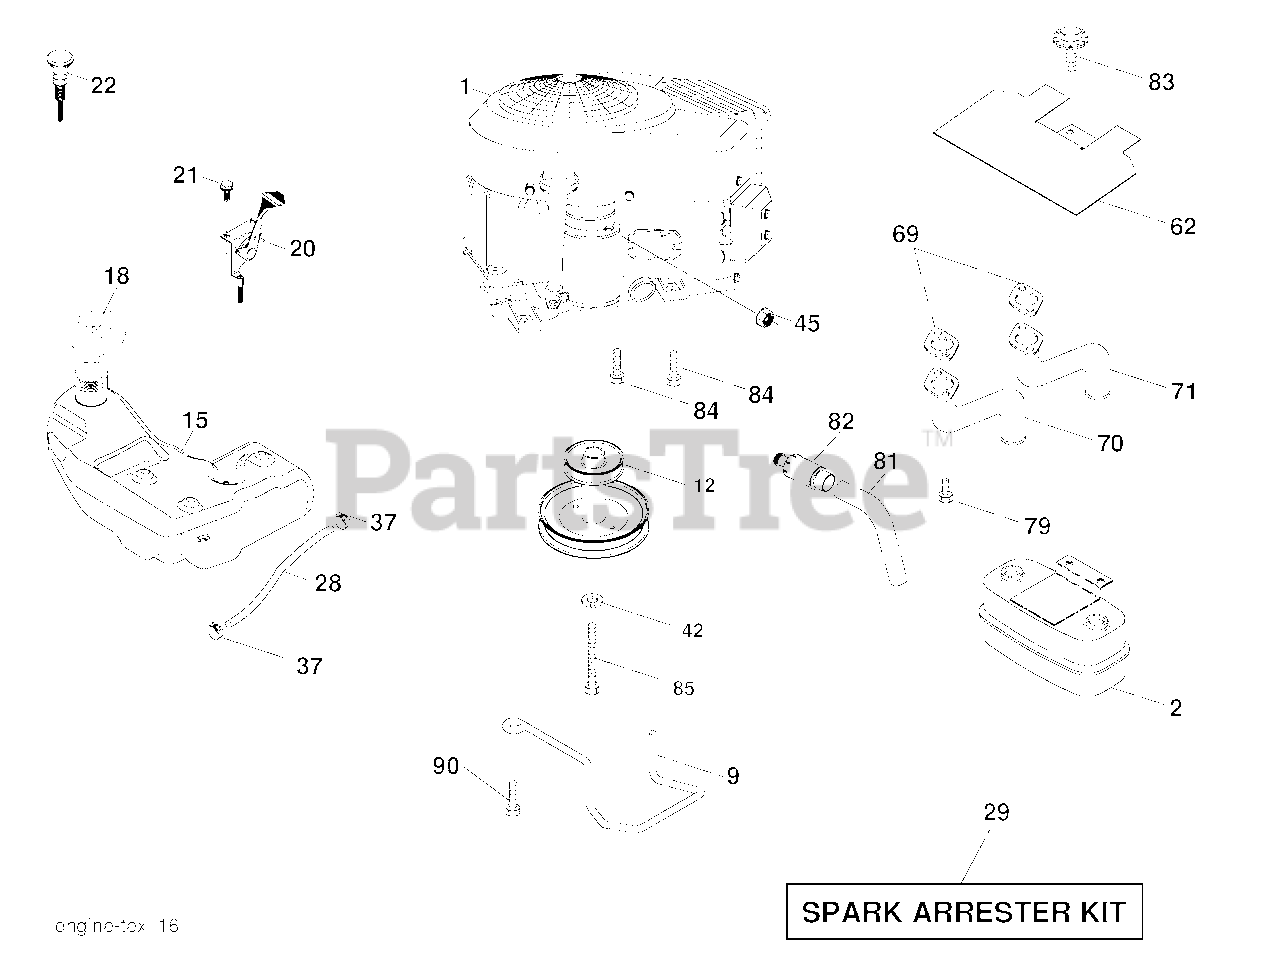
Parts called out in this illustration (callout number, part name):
2	Muffler
9	Keeper Belt Engine
12	Pulley Engine
15	Tank Fuel
18	Cap Asm
20	Control Throttle
21	Screw 10 x 3/4 Single Lead-
22	Control Choke
28	Fuel Line
29	Spark Arrester Kit
35	Washer Split
37	Clamp Hose
42	Washer Lock 7/16
45	Nut Keps Hex 1/4-20 unc
62	Shield Heat Muffler
69	Gasket
70	Exhaust Tube LH
71	Exhaust Tube RH
79	Screw Socket Head5/16-18 x 1
81	Tube Drain Oil Easy
82	Plug Drain Oil
83	Bolt 5/16-18 x 3/4 w/Sems
84	Screw 3/8-16 x 1-1/4
85	Bolt Hex 7/16-20 x 4 x Gr. 5-1.5
90	Screw 3/8-16 x 1
